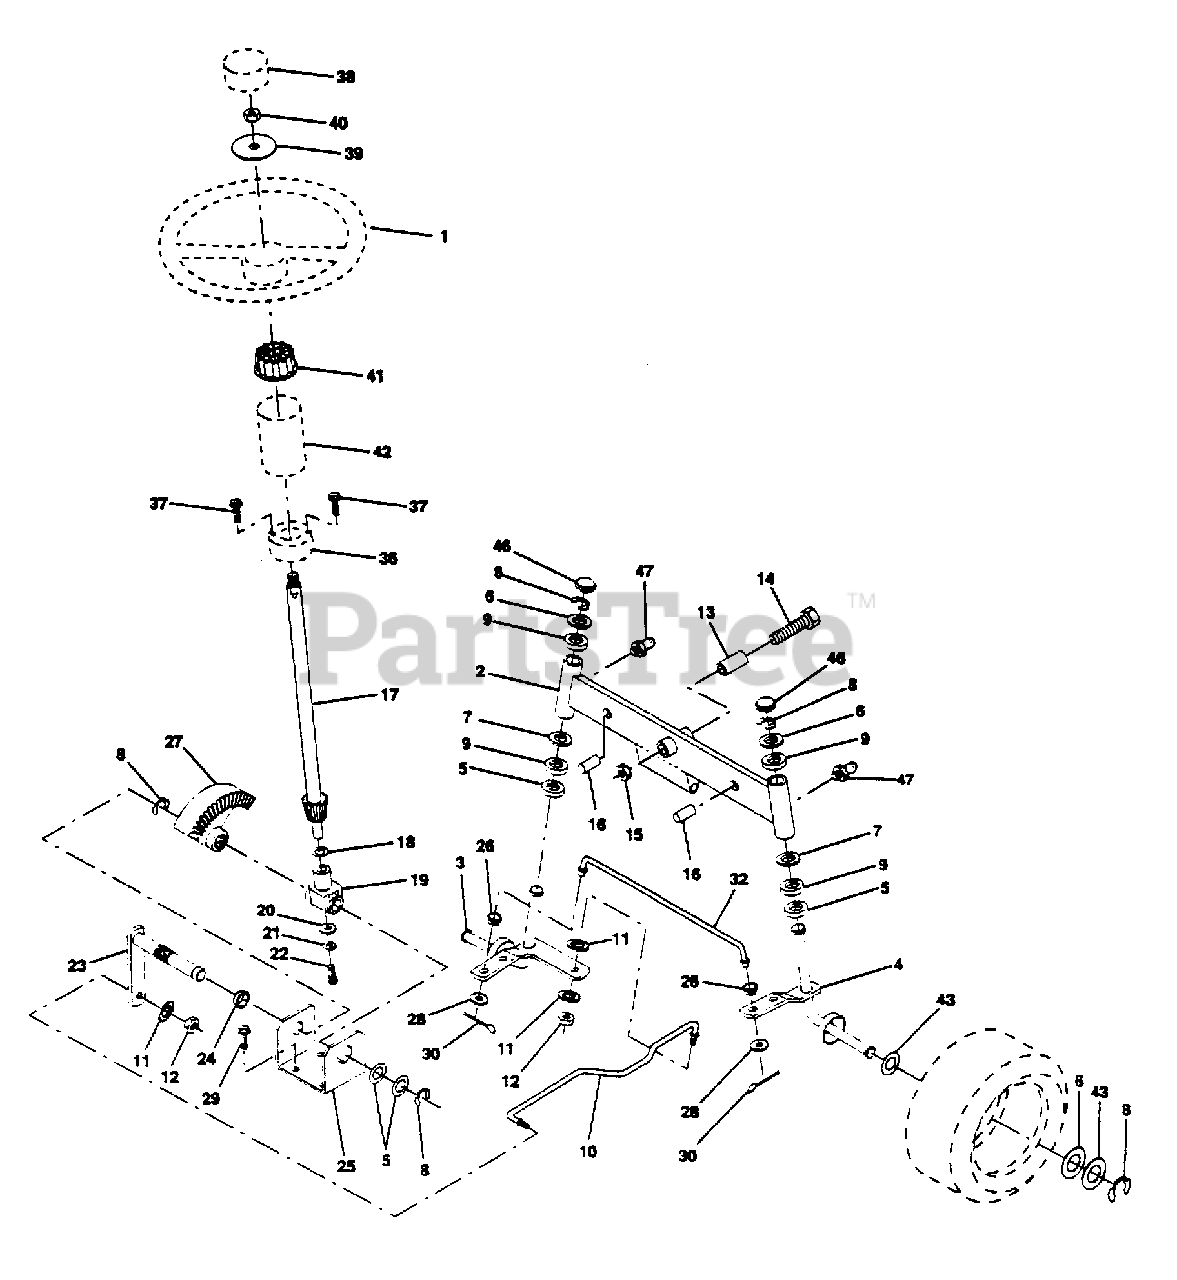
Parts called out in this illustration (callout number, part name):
2	AXLE ASM FRONT
3	SPINDLE LH
4	SPINDLE RH
5	WASHER .T
6	WASHER
7	WASHER
8	RING
9	COL. SRTG. BEAR.
11	LOCKWASHER
13	BEARING
14	BOLT HEX 5/8-11
15	"NUT-LOC,FLANGE LT"
16	AXLE PIN
17	SHAFT ASM
18	THRUST WASHER
19	SUPPORT.SHAFT
21	LOCKWASHER
22	"SCREW,SPECIAL"
24	NYLINER T
25	"BRKT,STEERING"
26	BUSHING.DRAGLINK
27	GEAR SECTOR
28	WASHER
29	SCREW
30	COTTER PIN
32	TIE ROD
38	ST WHL INSERT CAP
39	WASHER T
40	GRIPCO NUT
41	ADAPTER-WHEEL LT
42	"TUBE, STR SHAFT"
43	WASHER
46	CAP
47	ZERK M
